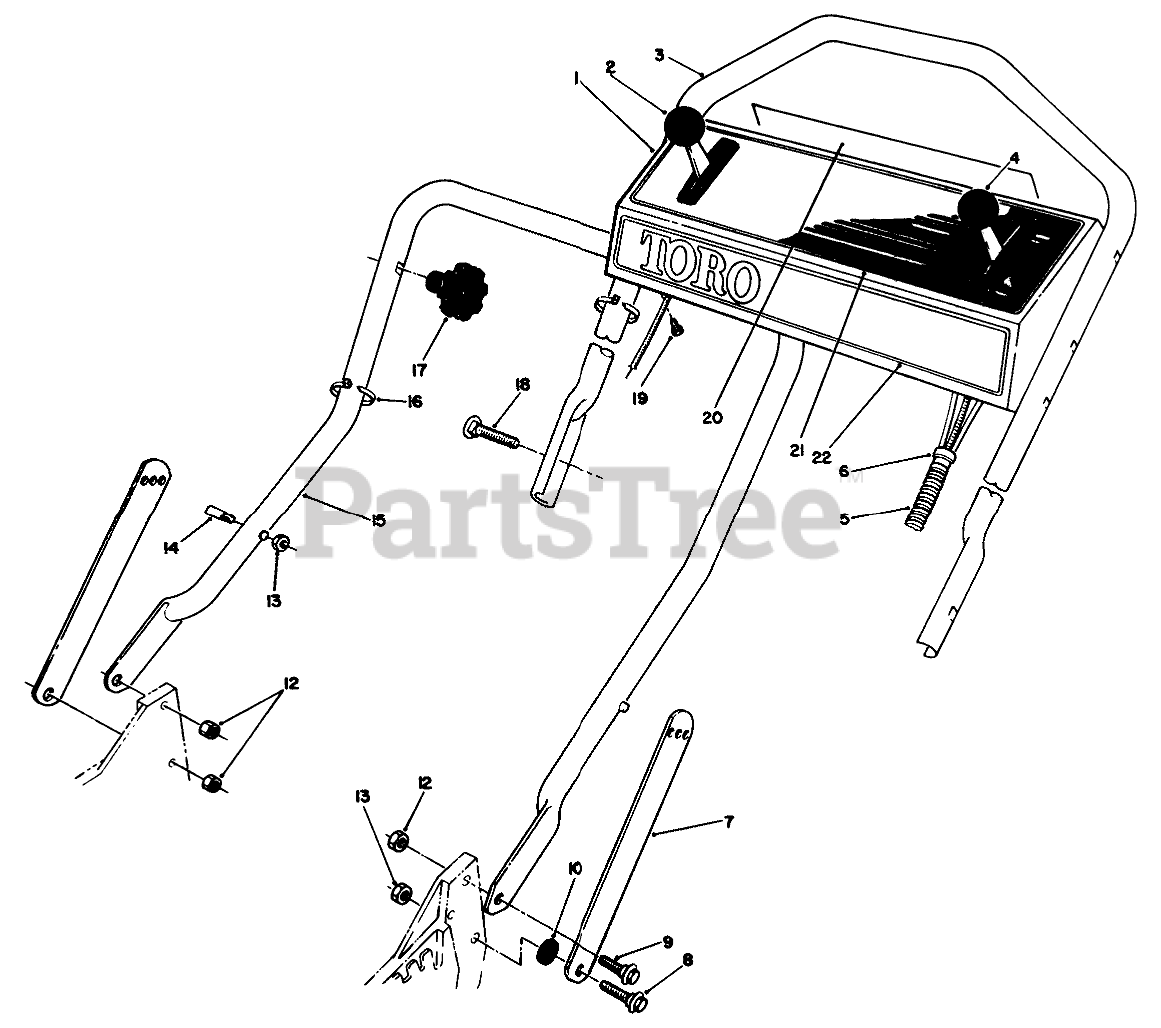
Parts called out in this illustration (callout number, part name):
1	Panel-Control
2	GROUND SPEED CONTROL
3	Handle-Upper
4	THROTTLE CONT-SERVICE
5	CONTROL CABLE COVER
6	FITTING-RING
7	Handle Latch
8	SCREW-SHOULDER
9	SCREW-SHOULDER
10	SPACER
12	NUT-LOCK, NI
13	NUT-LOCK, NI
14	HANDLE PIN
15	LOWER HANDLE ASM
16	TIE-CABLE
18	5/16-18 X 2 HNDLE SCREW
19	SCREW-HWHTF
20	DECAL - PANEL, REAR
21	Decal-Instructions
22	DECAL - TORO PANEL
